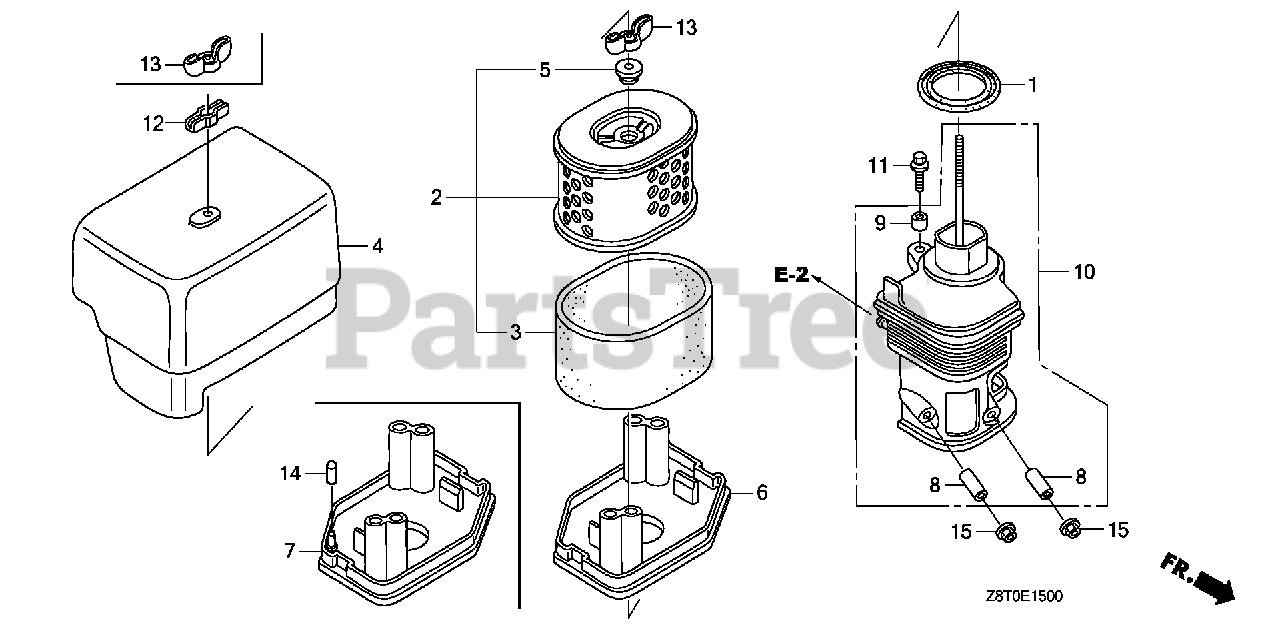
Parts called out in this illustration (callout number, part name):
1	GASKET, ELBOW
2	ELEMENT, AIR CLEANER
3	FILTER (OUTER)
4	COVER, AIR CLEANER
5	GROMMET, AIR CLEANER
7	NOSE, MUFFLER
8	COLLAR, AIR CLEANER
9	COLLAR B, AIR CLEANER
10	ELBOW, AIR CLEANER
11	BOLT-WASHER (6X22)
13	NUT, TOOL BOX SETTING
14	CAP, SEALING
15	NUT, FLANGE (6MM)
